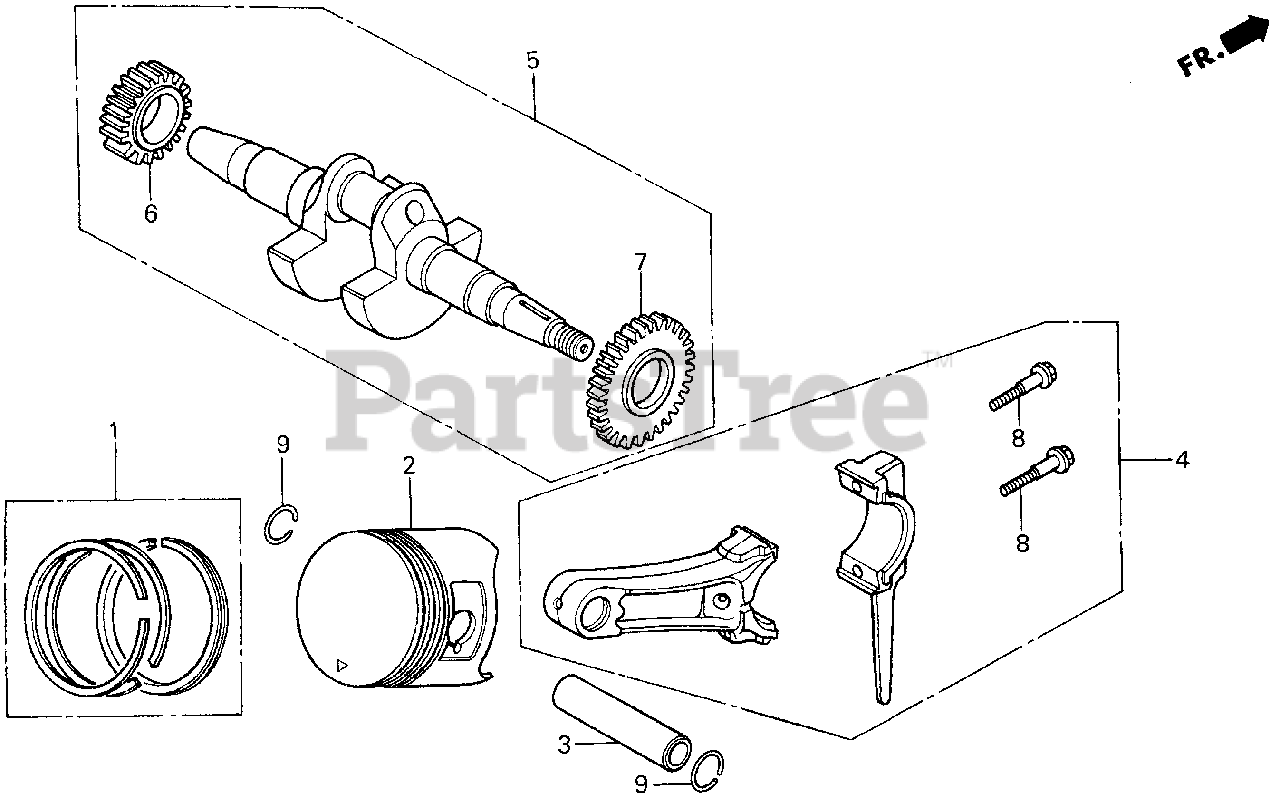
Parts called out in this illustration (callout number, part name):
1	RING SET, PISTON (STD)
1	RING SET, PISTON (OS 0.25) Use up to Engine SN 2120317.
1	RING SET, PISTON (OS 0.50) Use up to Engine SN 2120317.
1	RING SET, PISTON (0.75) Use up to Engine SN 2120317.
1	RING SET, PISTON (OS 0.25)
1	RING SET, PISTON (OS 0.50)
1	RING SET, PISTON (0.75)
2	PISTON (STD)
2	PISTON (OS 0.25)
2	PISTON (OS 0.50)
2	PISTON (0.75)
3	PIN, PISTON
4	ROD ASSY., CONNECTING
5	CRANKSHAFT (VE-TYPE)
6	GEAR, TIMING
7	GEAR, GOVERNOR DRIVE
8	BOLT, CONNECTING ROD
9	CLIP, PISTON PIN (18MM)
